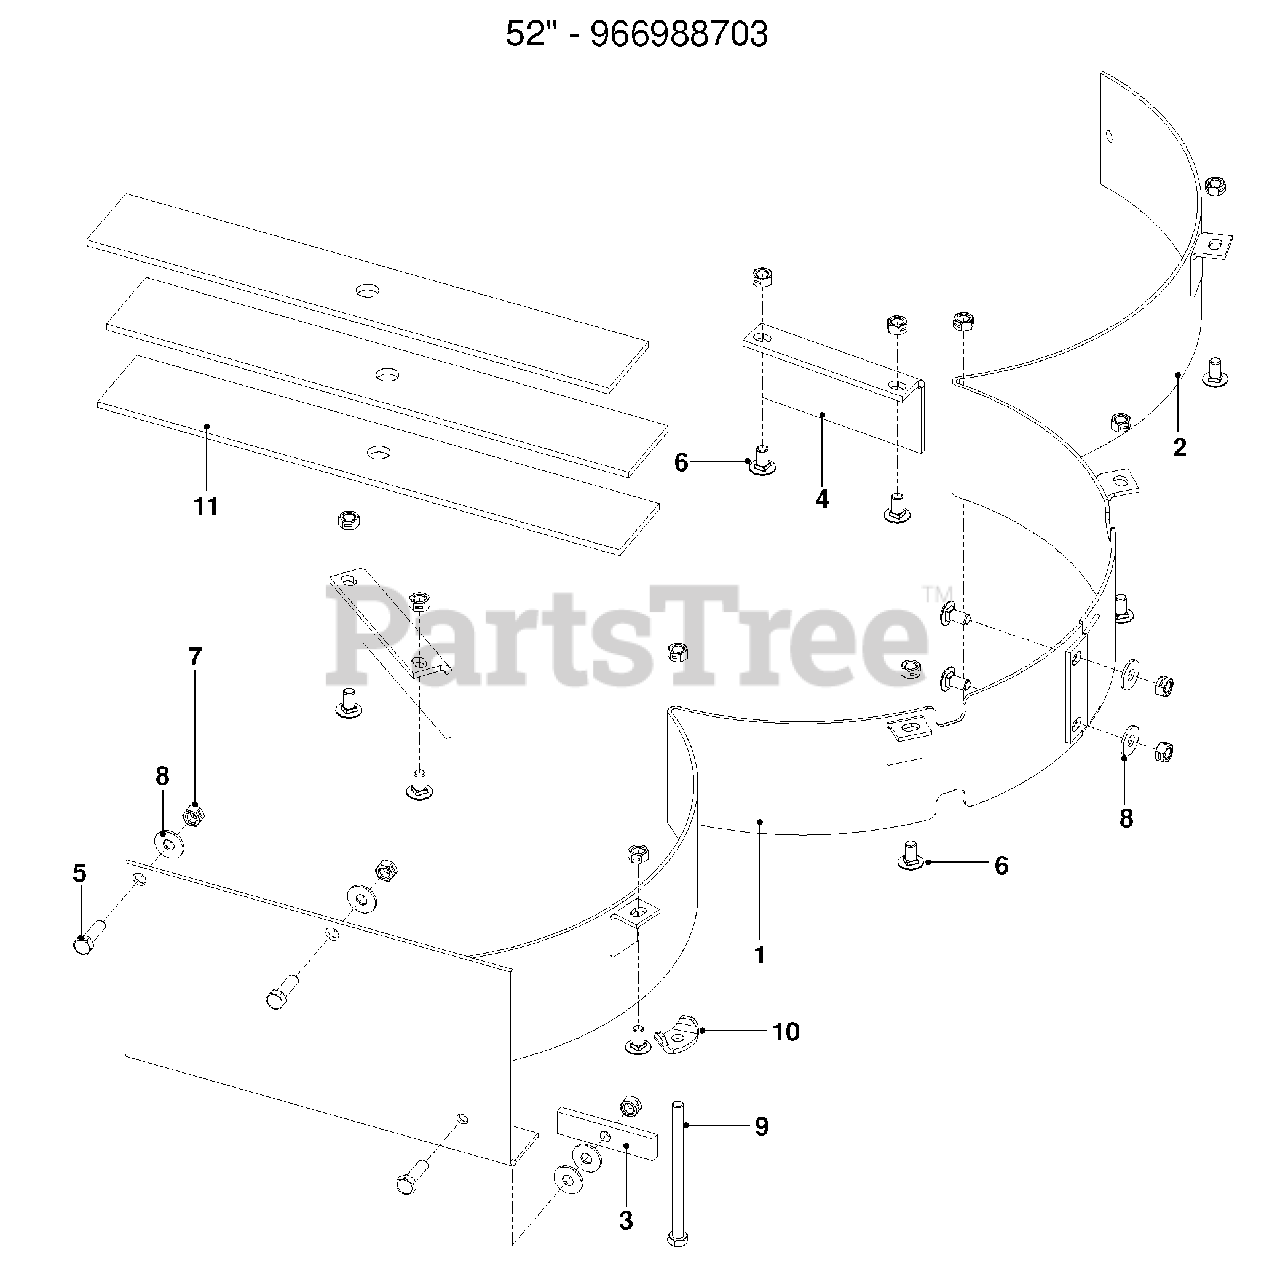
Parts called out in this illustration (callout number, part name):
1	Baffle Wldt, Black 52"
2	Mulch Wld-Lt
4	Deflector Center, 52"
5	Hcs 5/16-18 X 1 Gr 5
6	Rhsnb 5/16-18 X 5/8 Gr 5
7	Nut 5/16-18 Hex Ctrlk
8	Washer 5/16 Std Flt
9	Hcs 5/16-18 X 41/2 Gr 5
10	Cap, Black
11	Mulch Blade 18"
